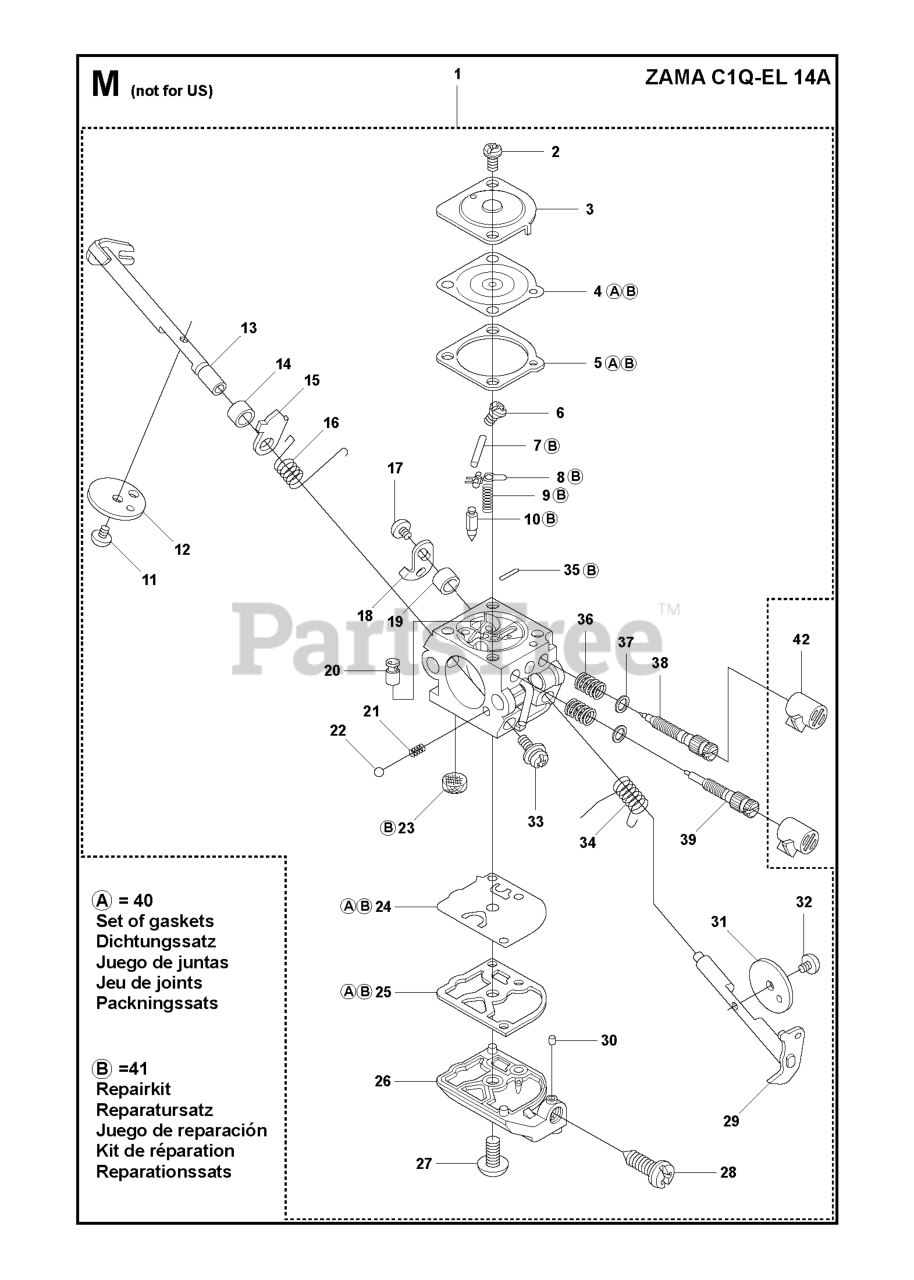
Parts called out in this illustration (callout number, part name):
1	CARBURETOR
7	PIN RETAINING SCREW
9	SPRING
10	INLET NEEDLE
12	DISC
13	CHOKE SHAFT
20	MAIN NOZZLE CH.VALVE
24	PUMP DIAPHRAGM
31	THROTTLE FLAP
34	SPRING THROTTLE
36	SPRING
38	LOW SPEED NEEDLE
39	NEEDLE HIGH SPEED
40	GASKET KIT (ZAMA GND39)
41	CARBURETOR KIT (ZAMA RB69)
